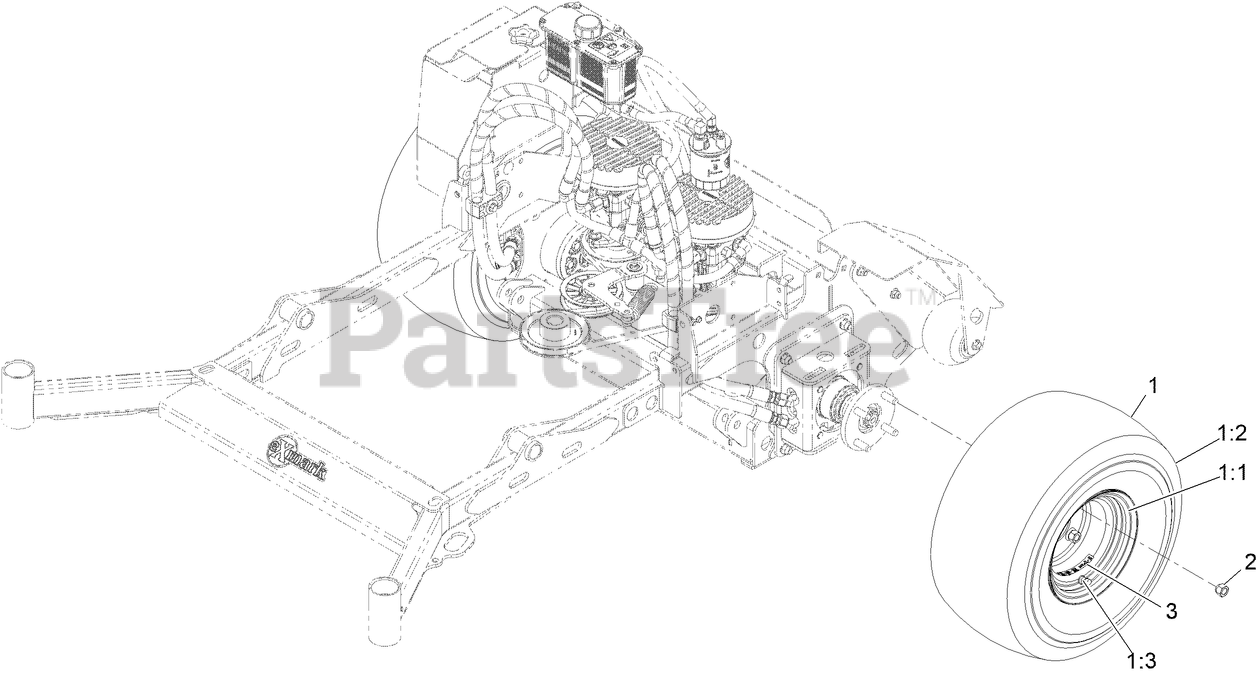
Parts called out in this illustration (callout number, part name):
1	Wheel/Tire ASM
1:3	VALVE
2	NUT-LUG
3	DECAL-TORQUE, WHEEL HUB LUG
